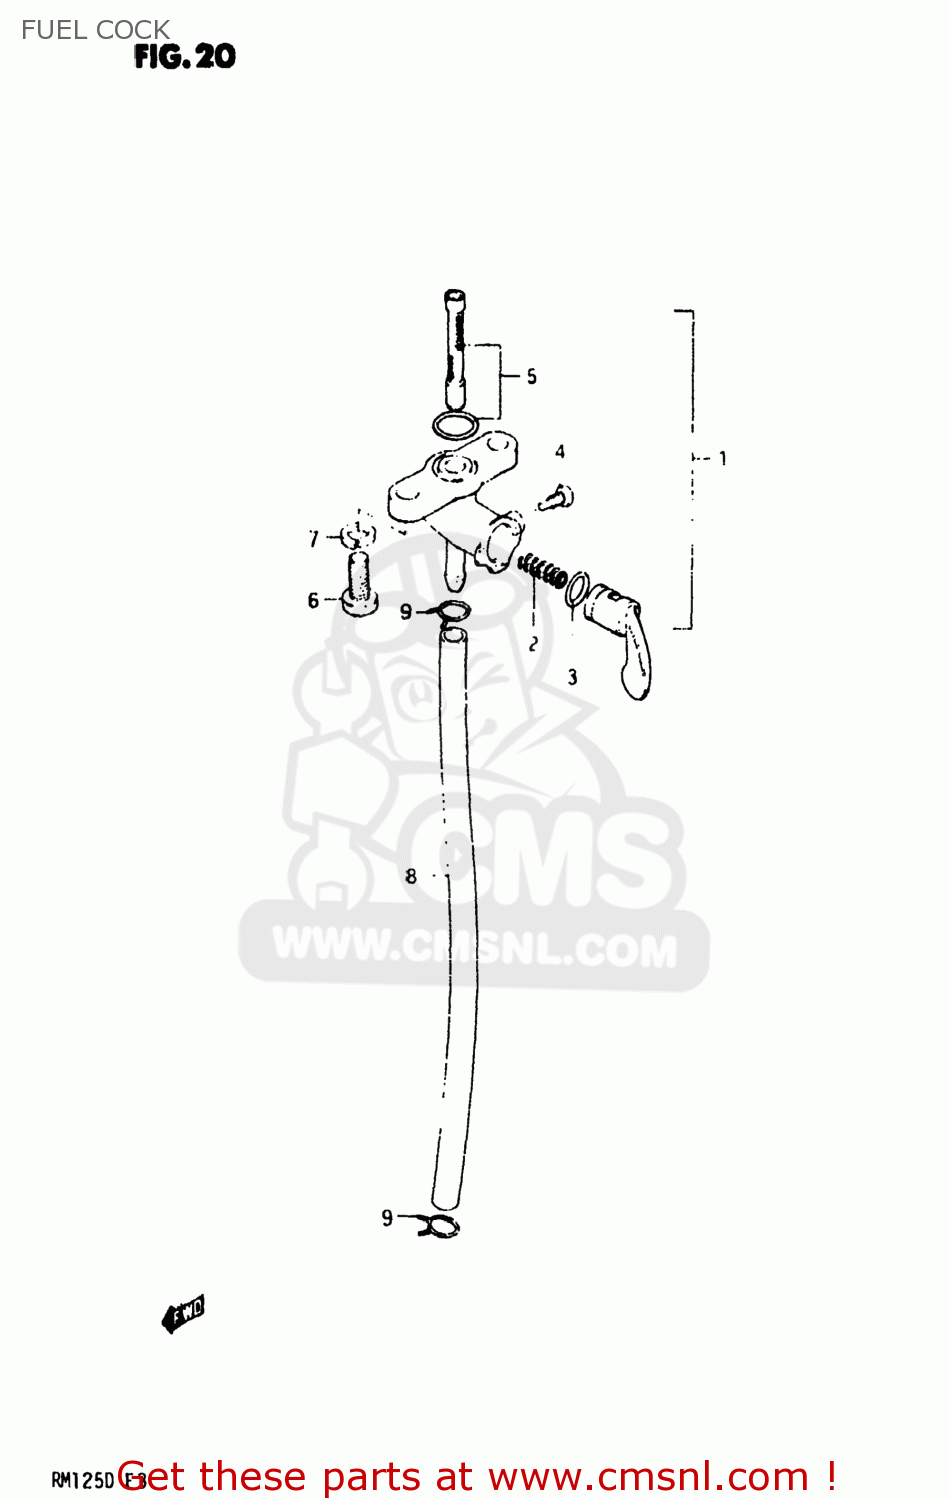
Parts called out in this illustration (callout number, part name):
1	COCK ASSEMBLY,FUEL
2	SPRING,FUEL COCK VALUE
3	O RING,LEVER
4	SCREW
5	FILTER SET FUEL
6	SCREW
7	LOCK WASHER
8	HOSE
9	CLIP
